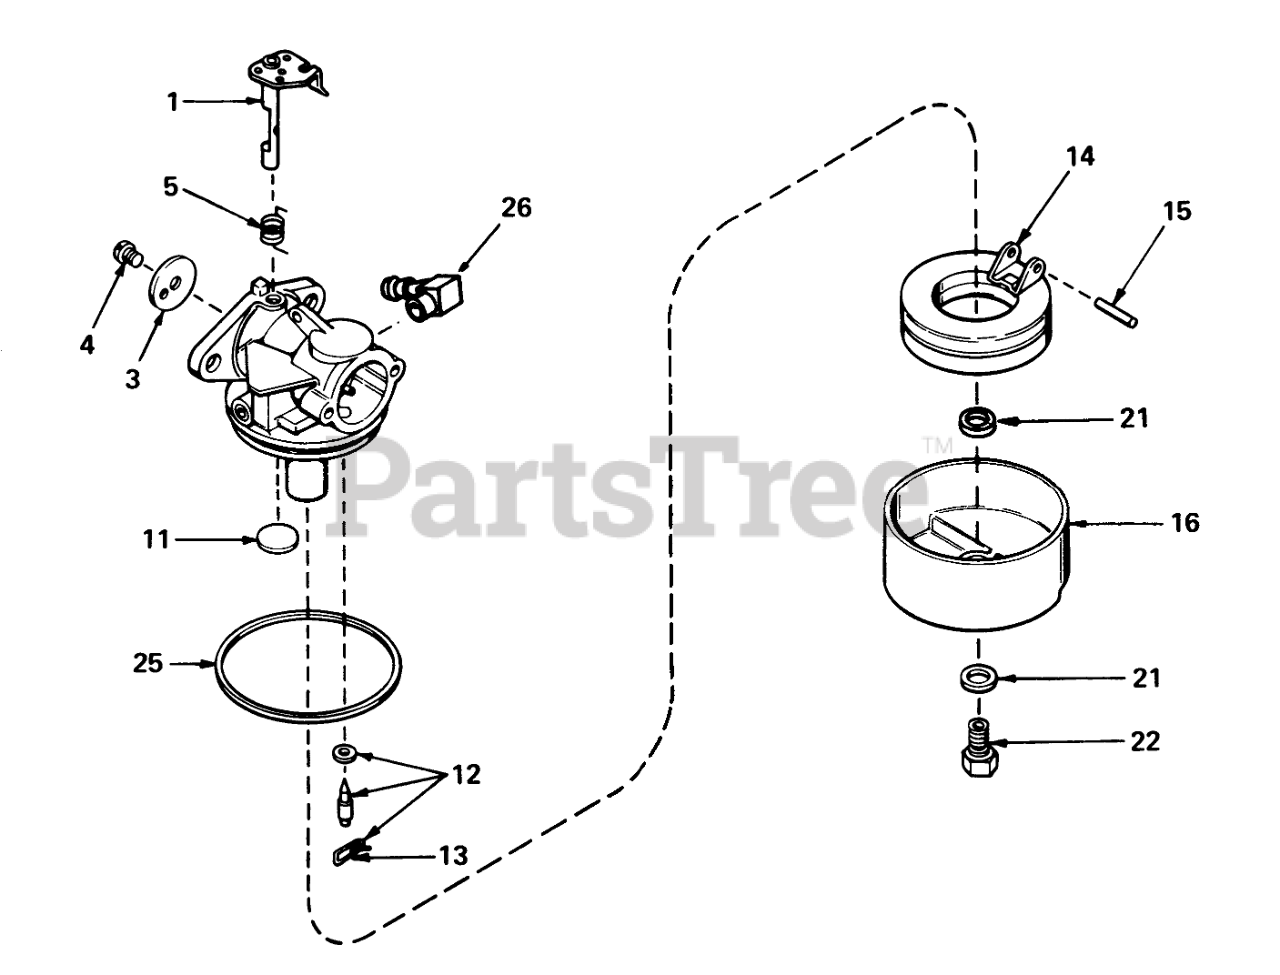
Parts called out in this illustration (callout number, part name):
1	Throttle Shaft and Lever ASM
3	Throttle-Shutter
4	Screw-Shutter
5	Spring, Return
11	Plug-Welch, Atmospheric Vent
12	Inlet Needle, Seat & Clip Assebmly (Incle. Ref. #13)
13	Clip-Spring
14	Float, Carburetor
15	Shaft-Float
16	Bowl Float
21	Gasket-Bowl
22	Nut-Float Bowl
25	O Ring-Bowl, Float
26	Fitting-Fuel
